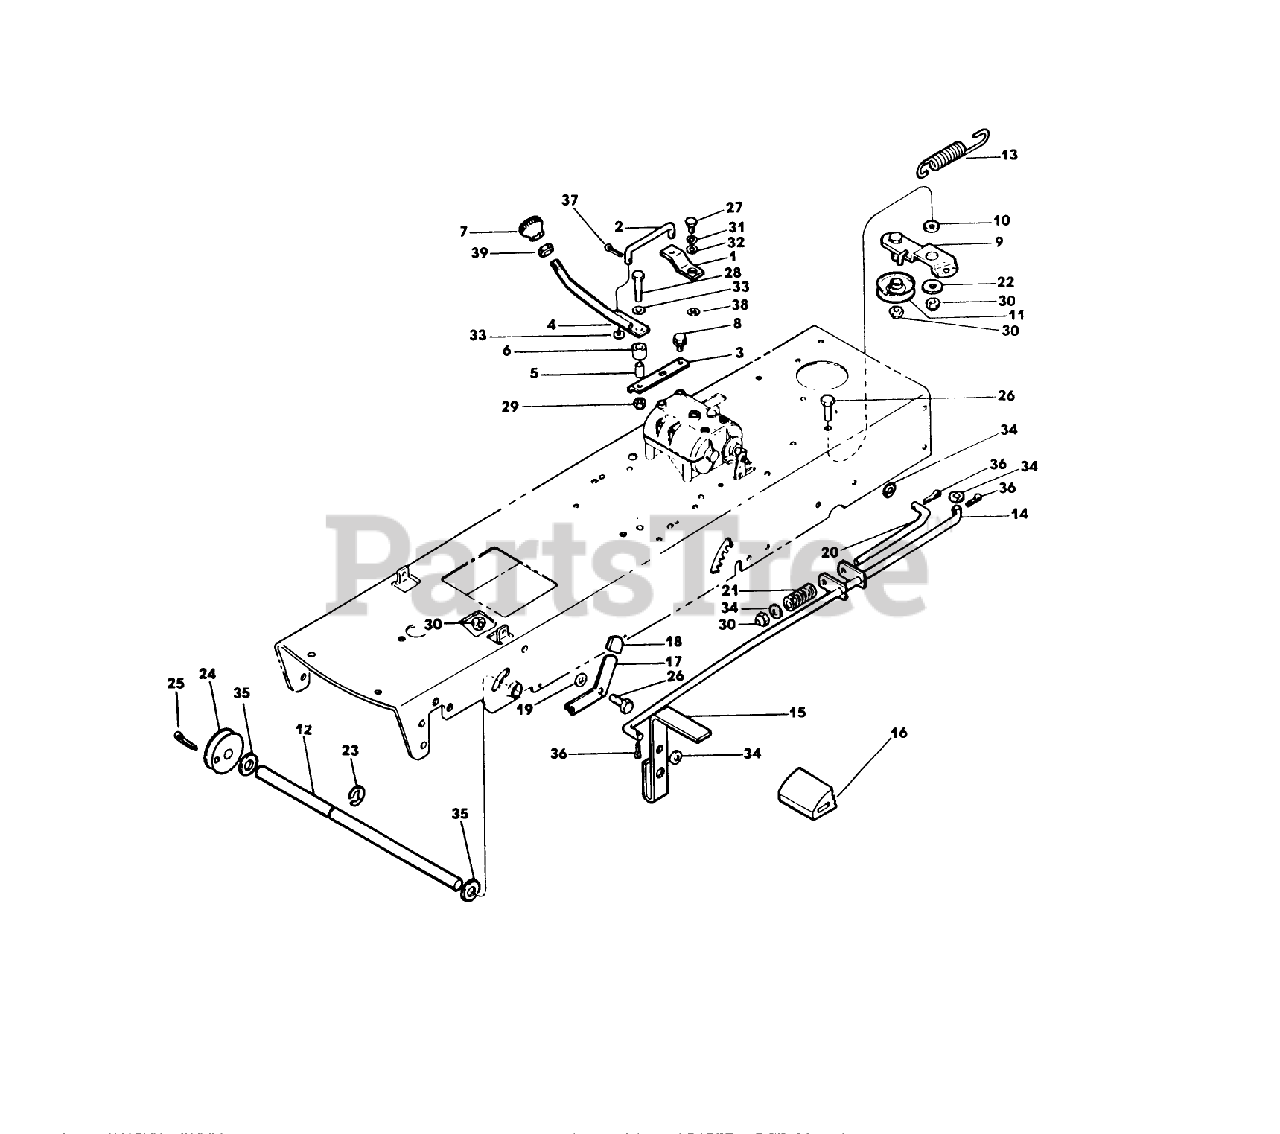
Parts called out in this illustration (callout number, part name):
1	PLATE-SHIFTER
3	BRKT - SHIFT MOUNT *B
5	SPACER
6	SPACER - RUBBER
8	SCREW
12	SHAFT - CROSS
13	SPRING
16	PAD - FOOT
27	SCREW-HEXHEAD
29	NUT
30	NUT-LOCKING
32	WASHER
34	WASHER
39	NUT-HEX
